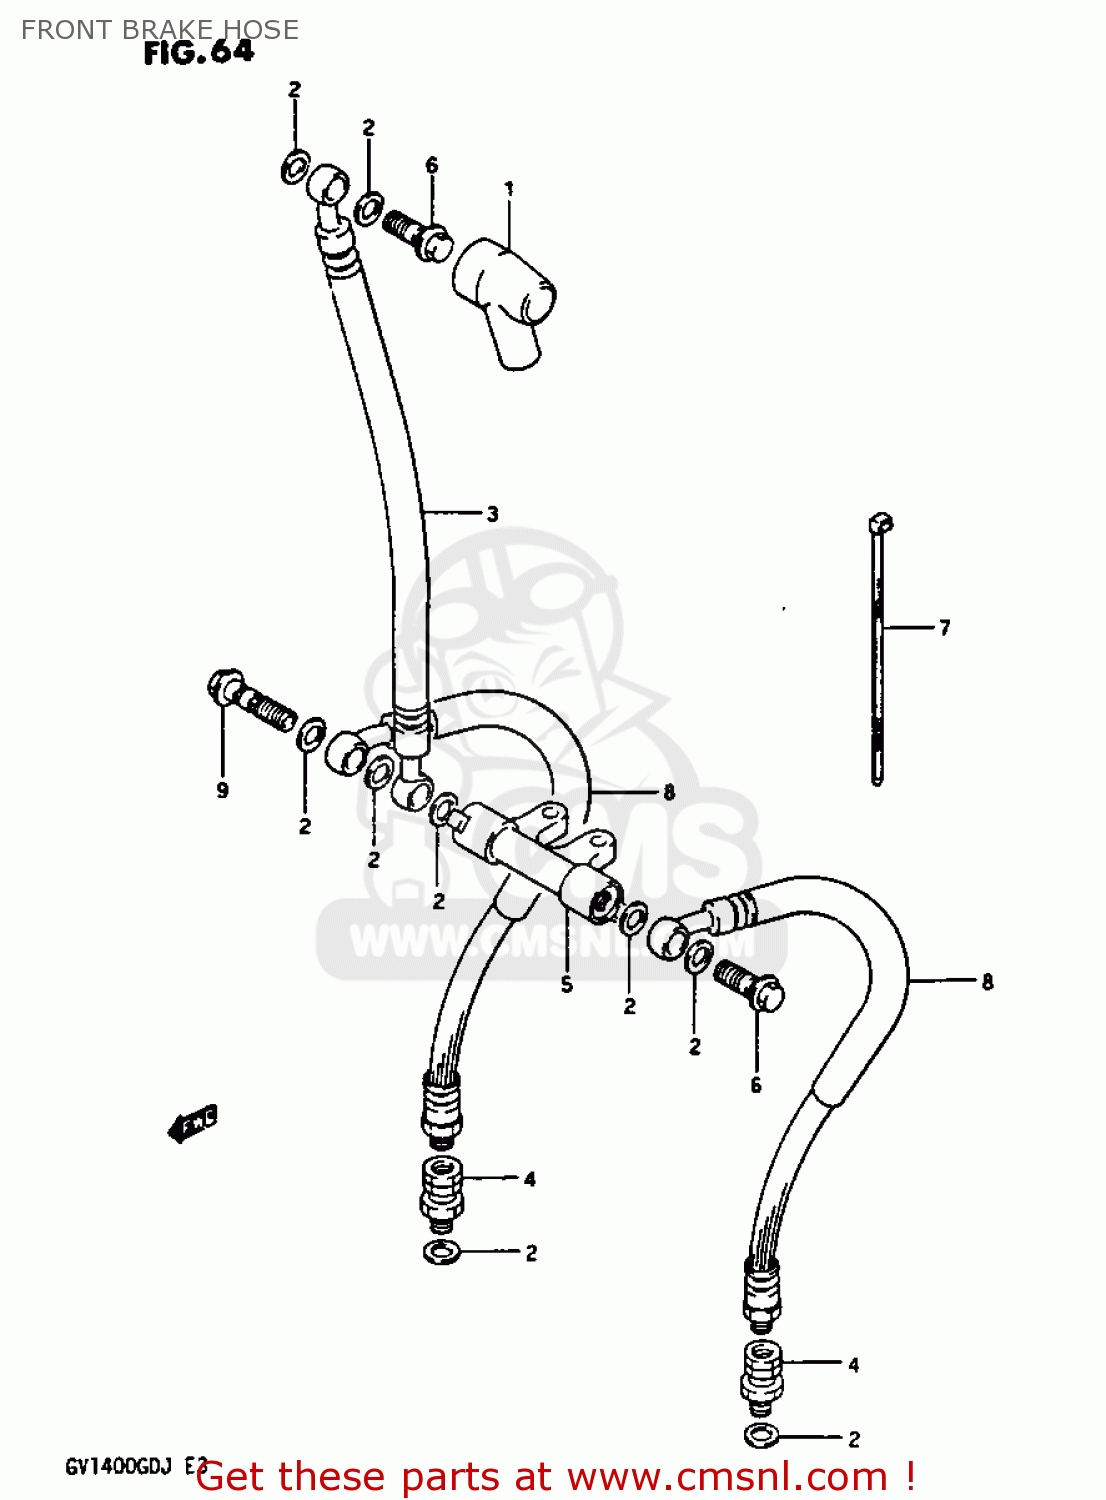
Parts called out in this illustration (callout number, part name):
1	BOOT,MASTER CYLINDER
2	WASHER(10X15X1.5)
3	HOSE,FRONT BRAKE
4	ADAPTER,BRAKE HOSE
5	JOINT,BRAKE HOSE
6	BOLT UNION
7	CLAMP(L:250)
8	HOSE,FR BRAKE NO.2
9	BOLT UNION
